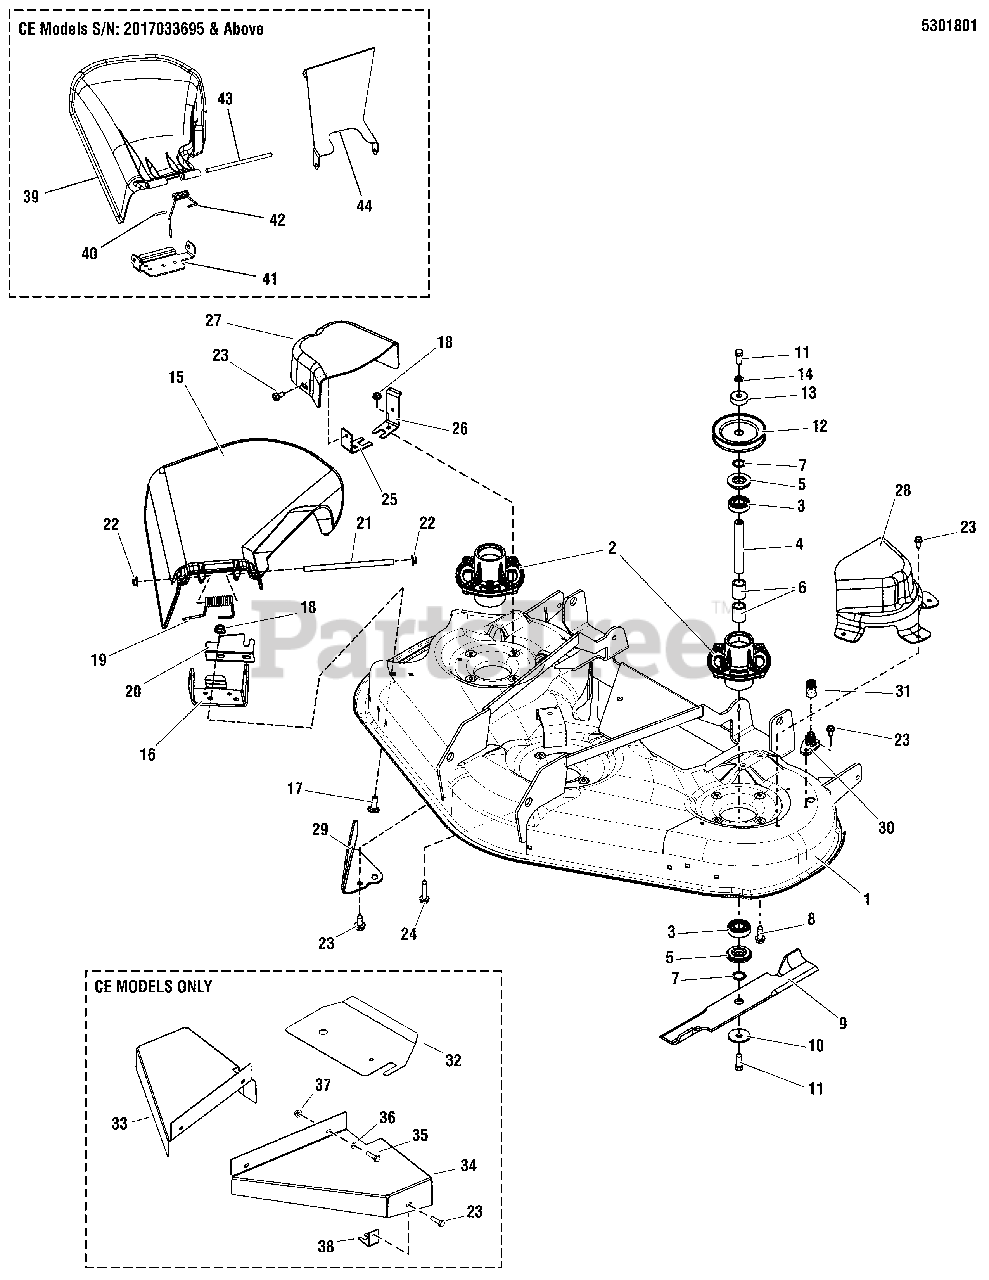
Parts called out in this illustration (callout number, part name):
1	DECK SHELL W/ DECALS, 52, SMI CHAMP
2	HOUSING, SPINDLE, CAST STEEL, MACHINED
3	BEARING-BALL 20MM 46" MWR
4	SHAFT-SPINDLE 20MM DIA 134.60MM LG
5	SHIELD-ARBOR 2.050OD 46" MWR
6	SPACER-BEARING PWDR MTL 46" MWR
7	RING-SELF LOCKING 46" MWR
8	SCREW-HEX WSHR HD TAPTT5/16-18X1.000BLK
9	BLADE-MOWER 18.50LG 52" MWR
10	WASHER, SPRING 0.475IDX1.75ODX.156TH BLK
11	CAPSCREW-HEX HD 7/16-14X1.000 G5 BLK
12	PULLEY-5.5 OD 11GA SPLIT 52" MWR
13	SPACER-LOWER DRIVE 46" MWR
14	LOCKWSHER-SPRING .438 BLK
15	DEFLECTOR-DISCH PLASTIC 46/52 DECKS
16	HINGE, DEFLECTOR, 52"
17	BOLT-RD HD SH SQ NK 5/16-18X0.750 G5 BLK
18	NUT, 5/16-18 HEX SERRATED FLANGE (SMALL)
19	SPRING-TORS DEFLECTOR 2.16LG 46" MWR
20	PLATE, DEFLECTOR CLOSEOFF
21	ROD, DEFLECTOR, YELLOW ZINC
22	NUT, PUSH, 5/16 BZ
23	SCREW-HEX WSHR HD TAPTT5/16-18X0.750BLK
24	SCREW-HEX WSHR HD TAPTT5/16-18X1.500 BLK
25	BRKT, BELT COVER, SHORT
26	BRKT, BELT COVER, LONG W/ TAB
27	COVER-BELT BLACK POLY RH 46 + 52" MWRS
28	COVER-BELT LH BLACK POLY 52" MOWER
29	BAFFLE, PINCHOFF
30	ADAPTER-WASHOUT PORT 46+52" PLASTIC
31	WASHOUT PORT-CONNECTOR 46+52" BLK POLY
32	PLATE, BELT GUARD
33	PLATE, DECK GUARD - ORG RH
34	PLATE, DECK GUARD - ORG LH
35	BOLT, 5/16-18 X 1 GD5 YZ
36	WASHER, 5/16 SAE
37	NUT, 5/16-18 HEX NYLOCK FLANGE
38	BRKT, BELT COVER, FRONT
39	DEFLECTOR, 46/52
40	CAP, PROTECTOR, .120 ID
41	BRACKET, HINGE, RETRO
42	SPRING - TORSION
43	ROD, DEFLECTOR 46"/52"
44	BRACKET, Support
